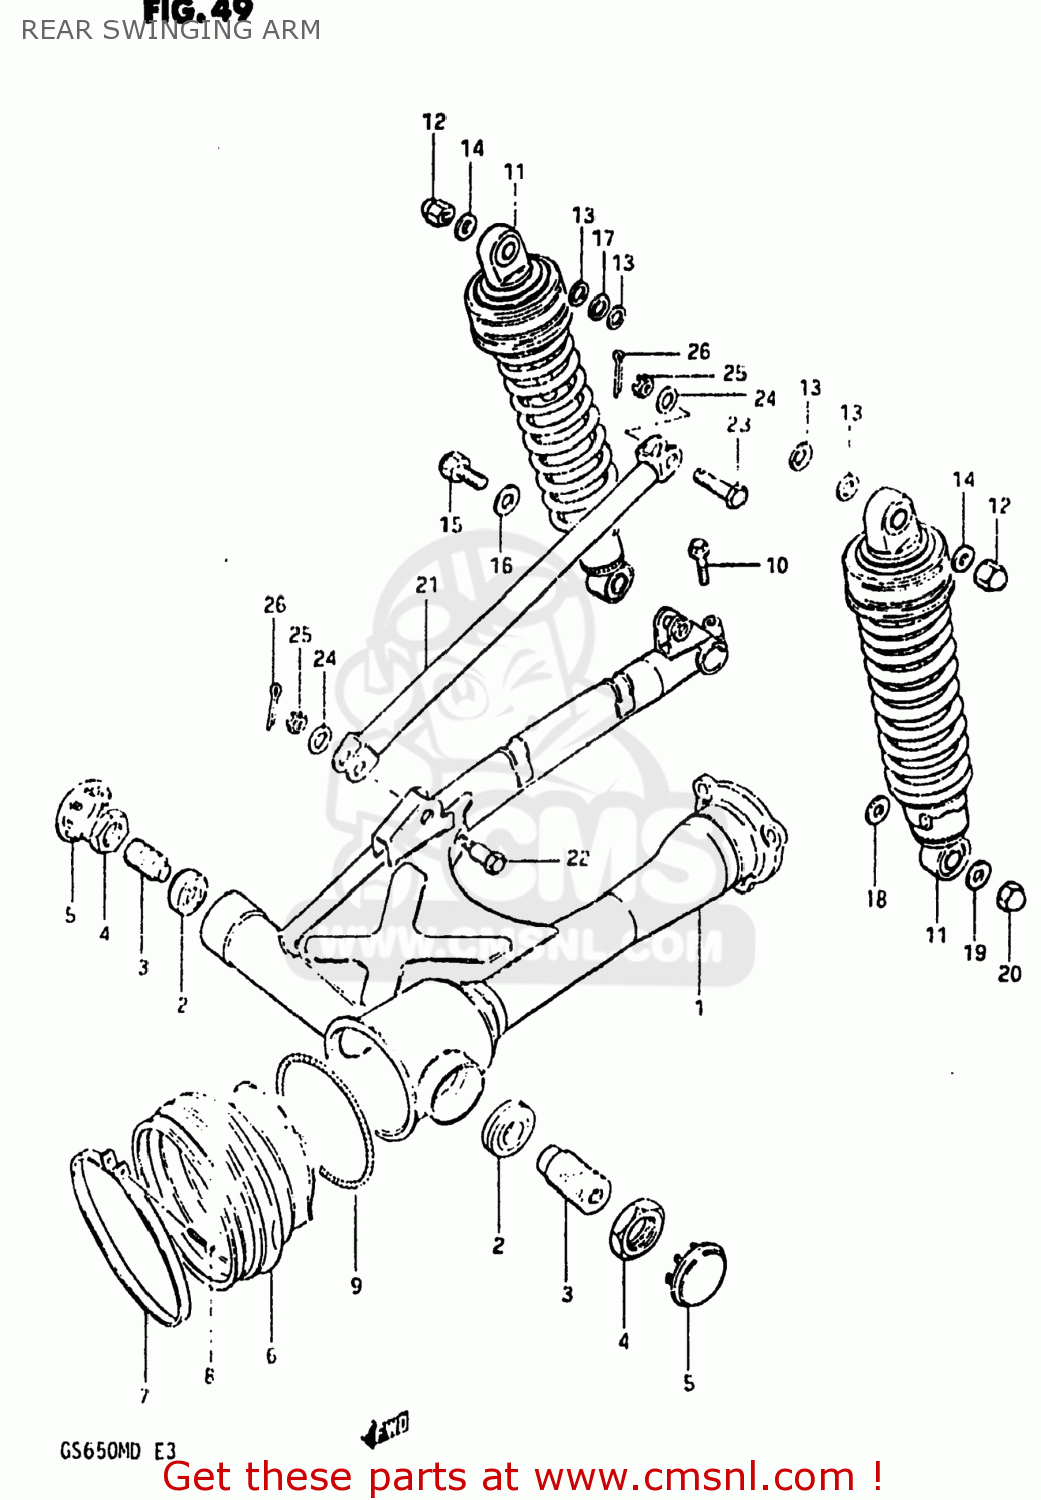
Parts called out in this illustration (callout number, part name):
1	ARM,REAR SWING
2	BEARING(15X35X11.75)
3	BOLT,REAR SWING ARM PIVOT
4	NUT (22MM)
5	CAP,REAR SWING ARM PIVOT
6	BOOT,PROPELLER SHAFT
7	CLAMP
8	SCREW 4X25
9	SPRING,PROPELLER SHAFT
10	BOLT
11	ABSORBER ASSEMBLY,REAR SHOCK
12	NUT
13	WASHER
14	WASHER
15	BOLT 12X33
16	WASHER (12.5X24X1.6)
17	WASHER (12.5X24X3.2)
18	WASHER
19	WASHER
20	NUT, LOWER LH
21	TORQUE LINK,REAR
22	BOLT
23	BOLT(10X39)
24	WASHER
25	NUT
26	PIN 20X20
